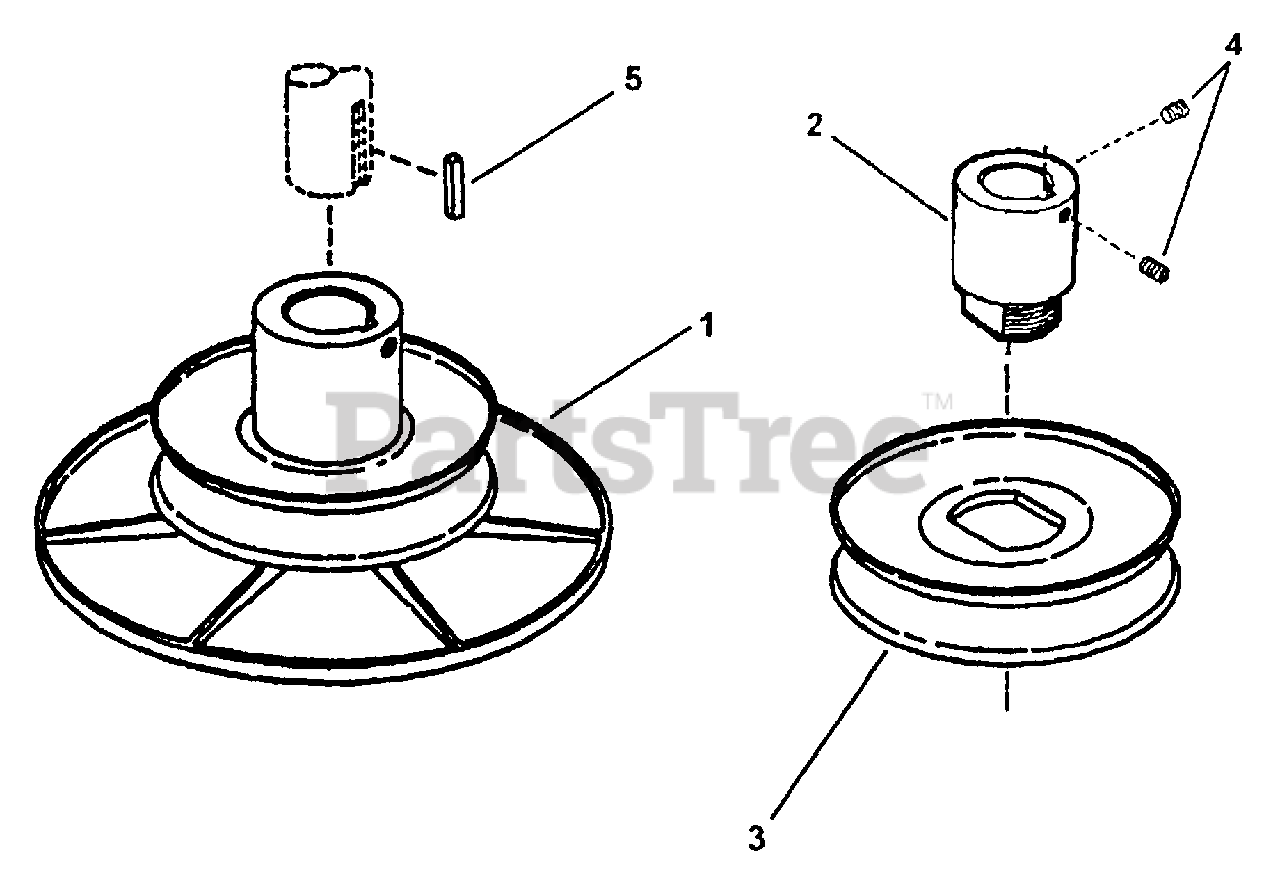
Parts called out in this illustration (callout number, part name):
1	ASSEMBLY, 5.18" O.D. Drive Disc
3	PULLEY, Drive
4	SCREW, 3/8-16 x 3/8" Set
5	KEY, 1/4" Square x 2"
